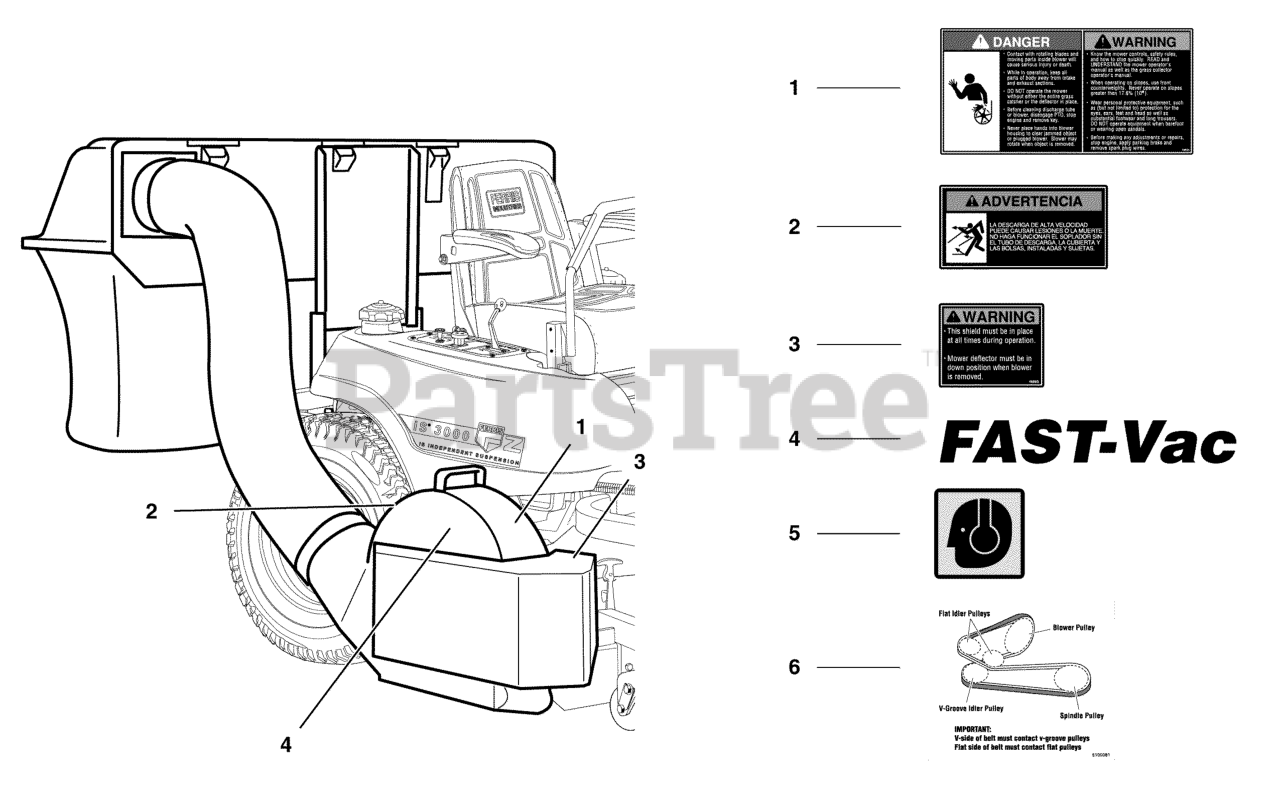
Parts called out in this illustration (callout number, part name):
1	DECAL, DANGER / WARNING
2	DECAL, WARNING-BLOWER
3	DECAL, WARNING-SHIELD
4	DECAL, FAST-VAC
5	(S) DECAL, EAR PROTECTION
6	DECAL, BELT ROUTING
